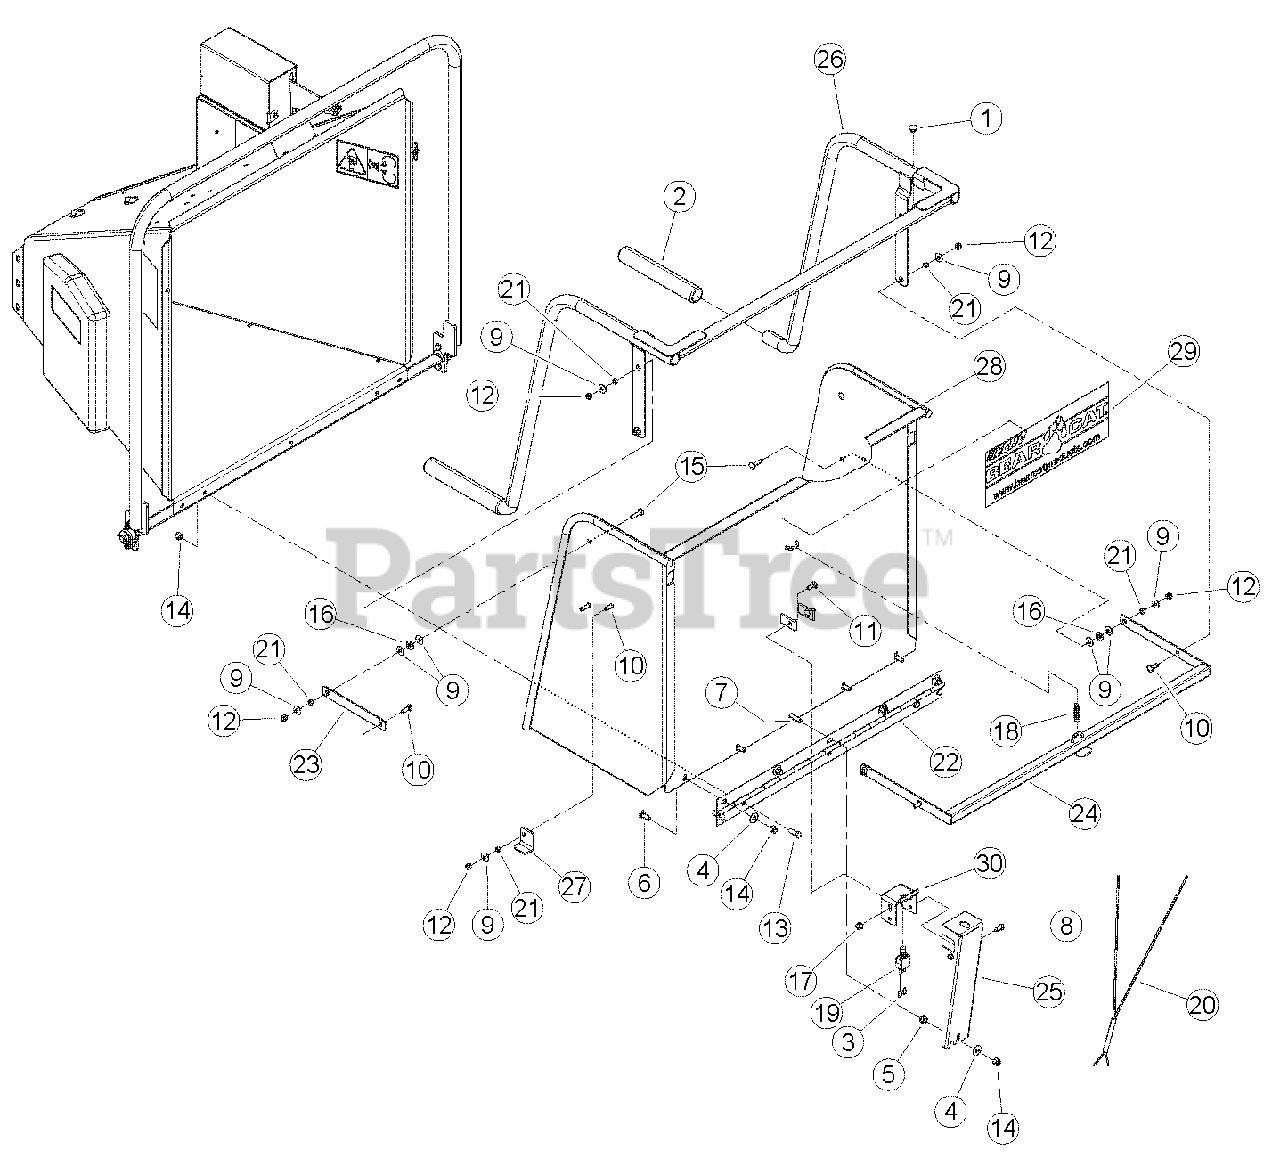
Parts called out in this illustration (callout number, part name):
1	BUMPER, RUBBER
2	GRIP, 1.219 X 10.00
3	CONNECTOR, 1/4 QD MALE
4	WASHER, 3/8 FLAT ZP
5	NUT, 3/8 SERR FLANGE ZP
6	BOLT, 3/8 X 1 CRG GR5 NC ZP
7	BOLT, 3/8 X 1-1/2 CRG GR5 NC ZP
8	SCREW, 11/32 X 7/8 HWH AB THREAD ZP
9	WASHER, 5/16 FLAT ZP
10	BOLT, 5/16 X 1 CRG GR5 ZP
11	BOLT, 5/16 X 7/8 CRG GR5 NC ZP
12	NUT, 5/16 NE NYLOCK ZP
13	BOLT, 3/8 X 1-1/4 HEX HD GR5 ZP
14	NUT, 3/8 NE NYLOCK ZP
15	BOLT, 5/16 X 1-1/4 CRG GR5 ZP
16	WASHER, 5/16 ID. X 7/8 OD. NYLON FLAT
17	NUT, 5/16-18 NYLOCK-FLANGE
18	SPRING 1/2 X 2.00 LG,ZP
19	SWITCH, MOMENTARY IP67 NORMALLY ON
20	HARNESS, SAFETY BAR
21	SPACER, IDLER PIVOT
22	HINGE, EXTENSION TRAY
23	LINK, PARALLEL
24	WELDMENT, KNEEBAR PIVOT
25	SHIELD, KNEEBAR SWITCH
26	WELDMENT, KNEEBAR
27	LOCK, SAFETY BAR
28	ASSEMBLY, EXT. TRAY, SERVICE PART
29	DECAL, BEARCAT WEB
30	ASSEMBLY, SWITCH BOX
